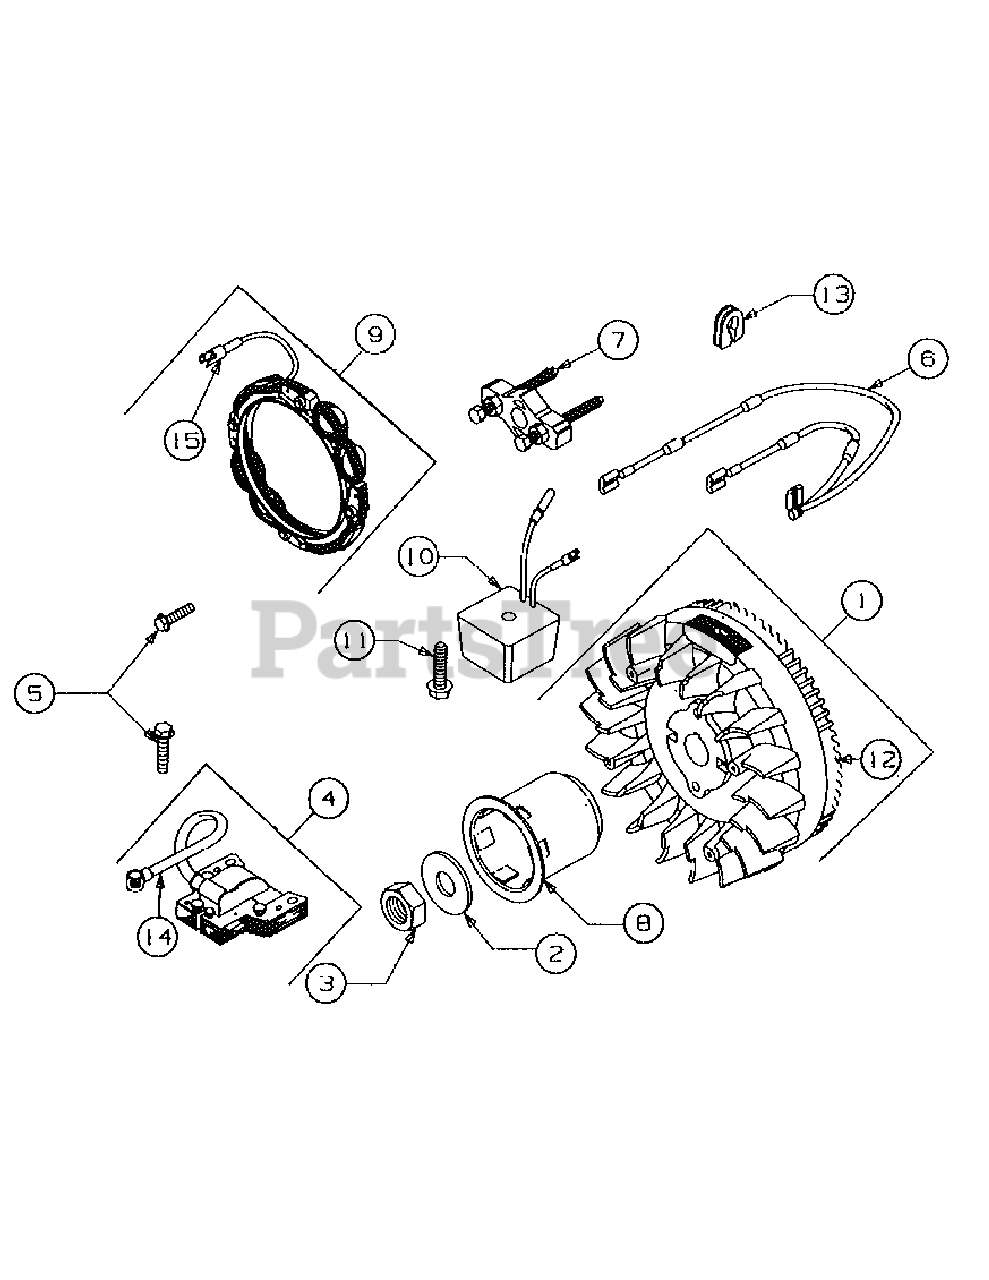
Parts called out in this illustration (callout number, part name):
1	Flywheel, Magneto
2	Washer, Spring
4	Armature, Magneto
5	Screw, Mounting
6	Wire Assembly
7	Puller, Flywheel
8	Hub, Starter
9	Stator, Alternator
10	Regulator, Alternator
11	Screw, Hex Head
12	Gear, ring
13	Grommet
14	Terminal, Ignition Cable
15	Connector Assembly
